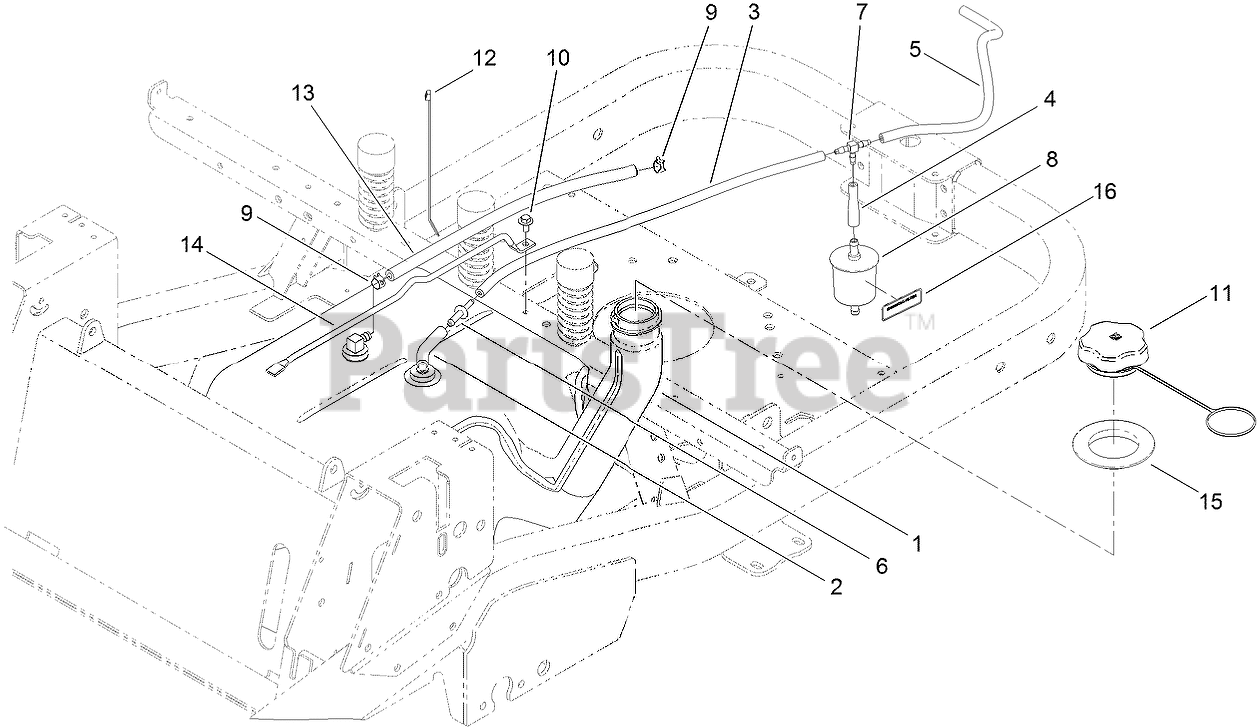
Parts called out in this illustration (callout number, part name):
1	FUEL TANK ASM
2	HOSE-FUEL
3	HOSE-FUEL
4	HOSE-FUEL, MOLDED
5	HOSE-FUEL
6	ADAPTOR-ORIFICE
7	FITTING-TEE
8	FILTER-FUEL
9	CLAMP-HOSE
10	SCREW-HHFTF
11	CAP-FUEL, RACHETING
12	TIE-CABLE
13	HOSE-FUEL
14	ROD-TANK, GAS
15	SEAL-TANK
16	DECAL-FILTER, EMISSIONS
